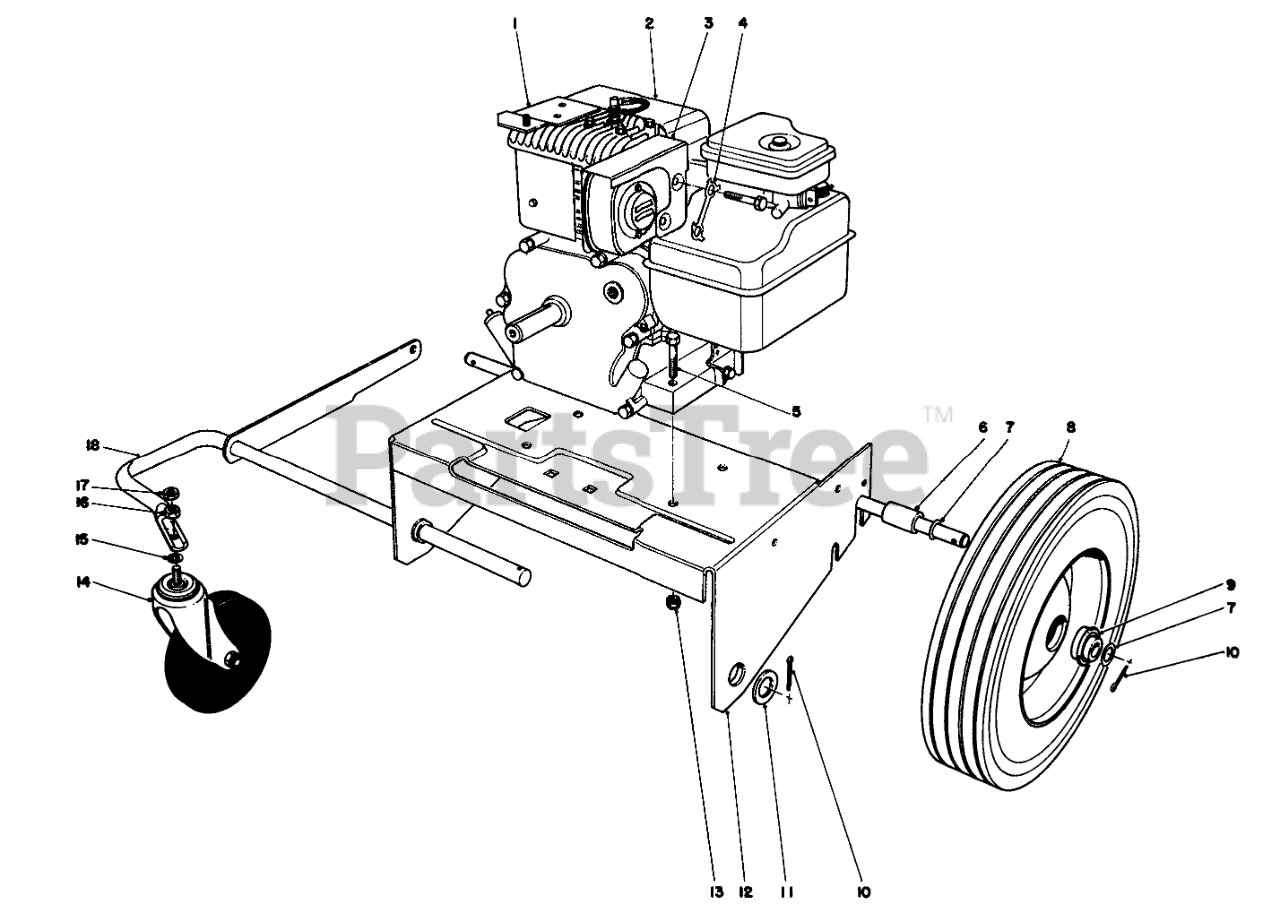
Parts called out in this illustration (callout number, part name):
1	MTG BRKT WA B
2	Engine
3	HEAT SHIELD
4	Lock Strip
5	SCREW-HH
6	SPACER-AXLE
7	WASHER
8	Wheel (Incl. Ref. #9)
9	BEARING
10	PIN-COTTER
11	WASHER-FLAT
12	Engine Plate
13	NUT-LOCK, CONE
14	CASTER
15	WASHER-LOCK/INT
16	NUT-HH
17	1/2-13 CONELOCK NUT
18	Front Wheel Support
